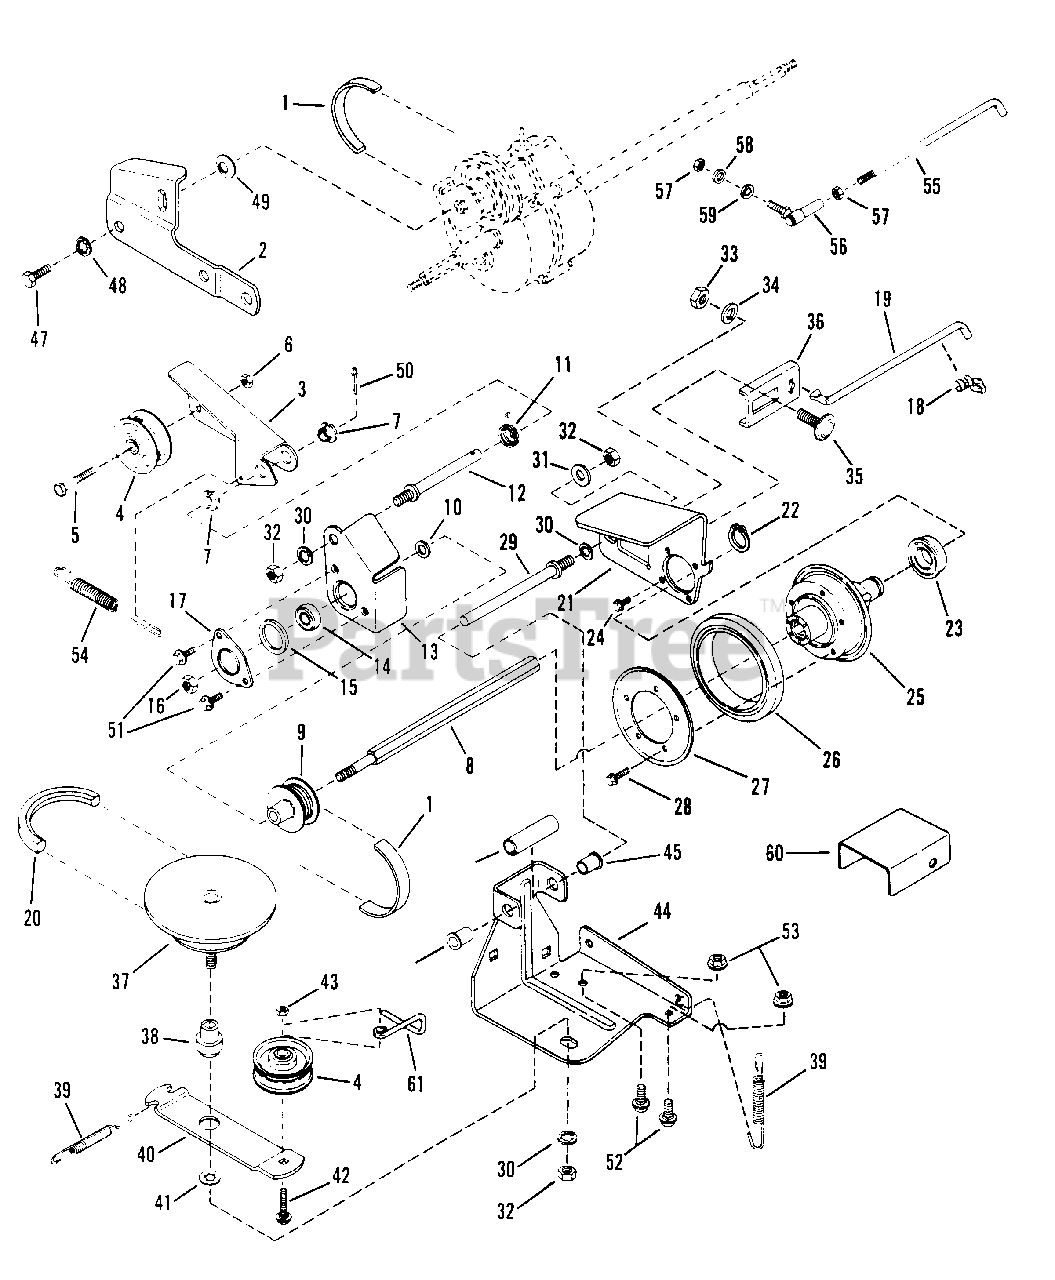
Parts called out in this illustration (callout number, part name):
1	BELT, Poly-Vee
2	LINK, Differential
3	ARM, Clutch Idler
4	PULLEY, Idler
5	SCREW, 1/4-28 x 1-3/8" Hex Head Cap
6	NUT, 1/4-28 Hex Lock
7	BUSHING, 3/8 I.D. Nylon
8	SHAFT, Hex
9	PULLEY, Poly-V
10	WASHER, 3/8" Flat
11	SPRING, Torsion
12	STUD
13	HOLDER, Bearing
14	BEARING, Ball
15	O-RING
16	NUT, 3/8-24 Hex Center Lock
17	HOLDER, Bearing
18	CLIP, 1/4 Right Arc
19	ROD, Transfer
20	BELT, Engine Drive
21	PLATE, Thrust
22	RING, Retaining
23	BEARING, Ball
24	SCREW, #10-32 x 1/4" Self-Tapping Machine
25	ASSEMBLY, Hub
26	RING, Driven
27	PLATE, Ring Retaining
28	SCREW, #10-24 x 1/2" Hex Washer Self-Tap (Torx)
29	GUIDE, Thrust Plate
30	WASHER, 3/8 Internal Tooth Lock
31	WASHER, 3/8" Flat
32	NUT, 3/8-24 Hex
33	NUT, 5/16-18 Hex
34	WASHER, 5/16 Split Lock
35	BOLT, 5/16-18 x 3/4" Carriage
36	CONNECTOR, Transfer Rod
37	ASSEMBLY, Drive Disc
38	BUSHING
39	SPRING
40	ARM, Idler
41	RETAINER, 3/8 Bolt
42	BOLT, 1/4-20 x 1-1/2" Carriage
43	NUT, 1/4-20 Hex Center Lock
44	BRACKET, Deck
45	BUSHING, Flange
47	SCREW, 5/16-18 x 1/2" Hex Head Cap
48	WASHER, 5/16 Internal Tooth Lock
49	WASHER, Spring
50	PIN, 3/32 x 1/2" Cotter
51	SCREW, 1/4-20 x 1/2" Self-Tapping
52	BOLT, 5/16-18 x 5/8" Short Neck Carriage
53	NUT, 5/16-18 x 5/8" Hex Flange Nut
54	SPRING, Clutch
55	LINK, Transfer
56	JOINT, Ball
57	NUT, 1/4-28 Hex
58	WASHER, 1/4 Flat
59	WASHER, 1/4 Internal Tooth Lock
60	SHIELD, Hex Shaft
61	SCRAPER, Drive Pulley
